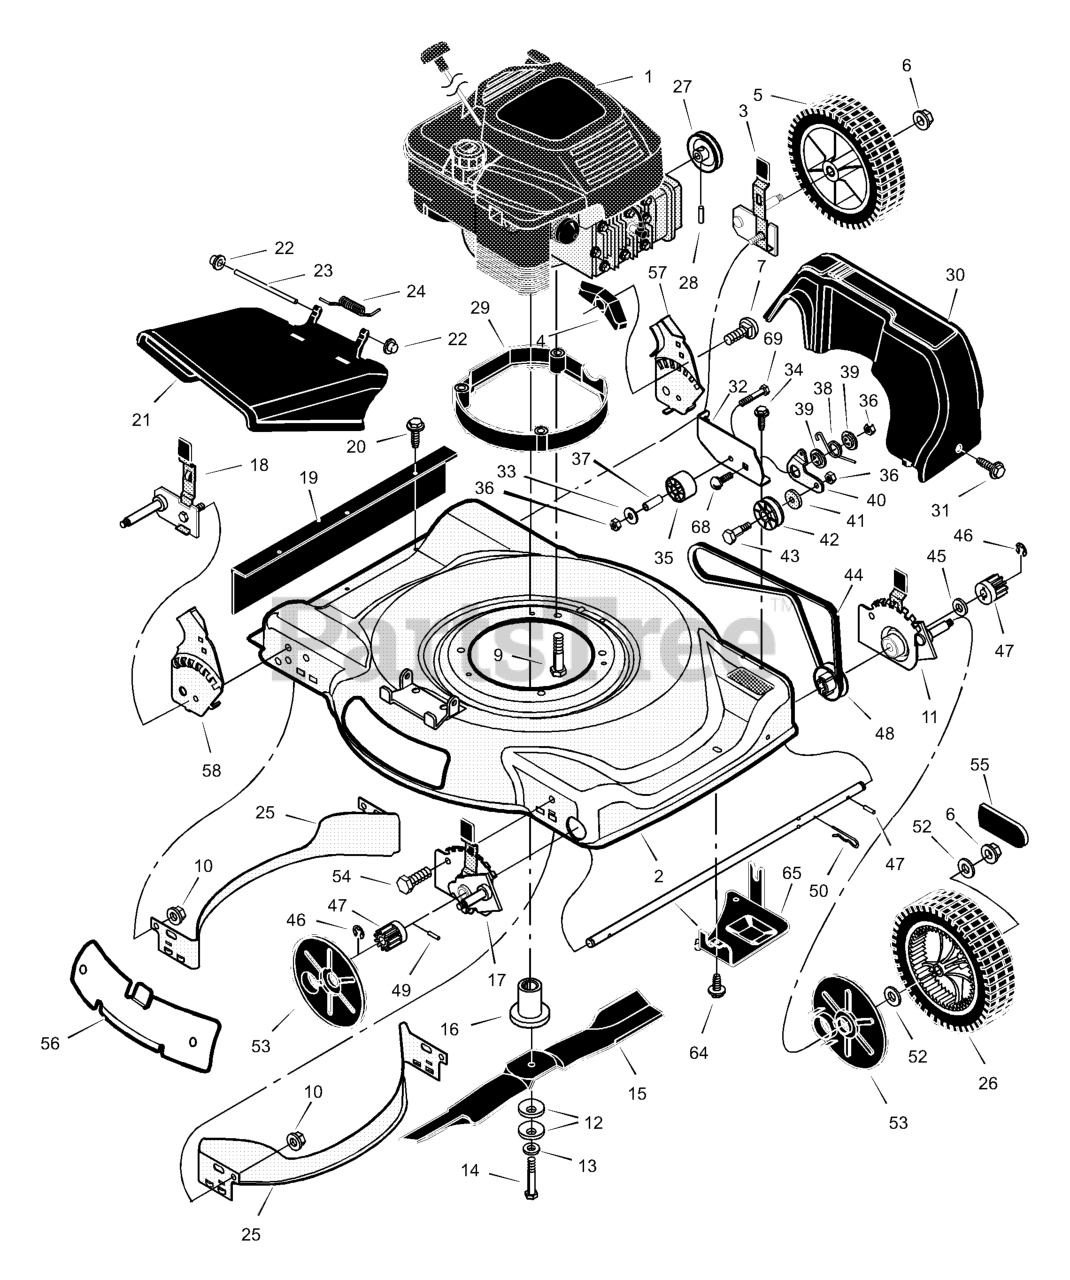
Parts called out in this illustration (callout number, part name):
1	Engine
2	Housing
3	Height Adjuster, Left Rear
5	Wheel and Tire, Rear
6	Locknut, Flange
7	Bolt, Carriage
9	Bolt, Engine
10	Nut
11	Height Adjuster, Left Front
12	Washer, Belleville
14	Bolt, Hex
16	Adapter, Blade
17	Height, Adjuster, Right Frt.
18	Height, Adjuster, Right Rr.
19	Guard, Rear
21	Deflector, Chute
22	Push-On Cap
23	Pin, Pivot
26	Wheel and Tire, Drive
28	Pin, Spring
29	Base, Engine
30	Cover, Belt (Black)
32	Bracket, Idler Support
35	Idler, Backside
36	Locknut
37	Bearing
40	Arm, Pivot
42	Pulley, Idler
43	Bolt, Shoulder
44	Belt, Briggs
46	Ring, Retainer
47	Gear, Pinion
49	Pin, Drive
50	Pin, Hair
52	Washer
53	Cover, Dust
54	Bolt
55	Hub Cap
56	Plate, Mulch
57	Bracket, Left Handle
58	Bracket, Right Handle
65	Shield, Debris
68	Bolt, Carriage
